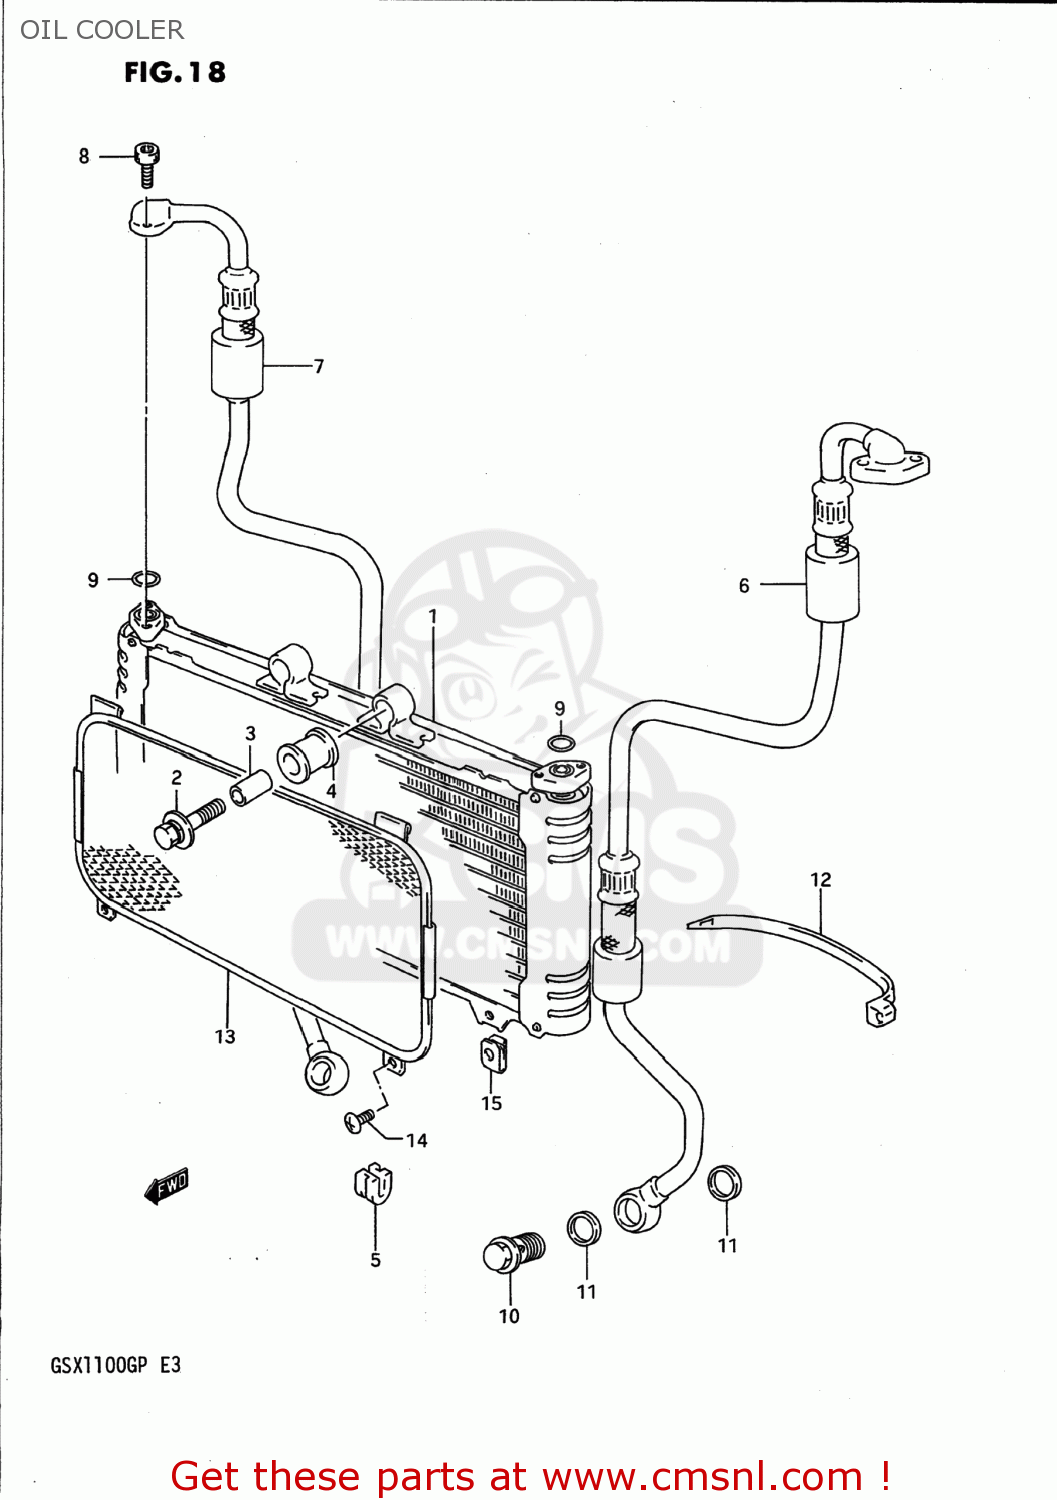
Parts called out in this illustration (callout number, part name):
1	COOLER,OIL
2	BOLT(8X40)
3	SPACER (8.8X12X24.5)
4	CUSHION,OIL COOLER NO.1
5	CUSHION,OIL COOLER NO.2
6	HOSE,OIL
7	HOSE,OIL
8	BOLT
9	O RING(D:2.4,ID:12.3)
10	BOLT UNION
11	GASKET(16X22X2) (NAS)
12	CLAMP(L:235)
13	NET,OIL COOLER
14	SCREW
15	NUT
